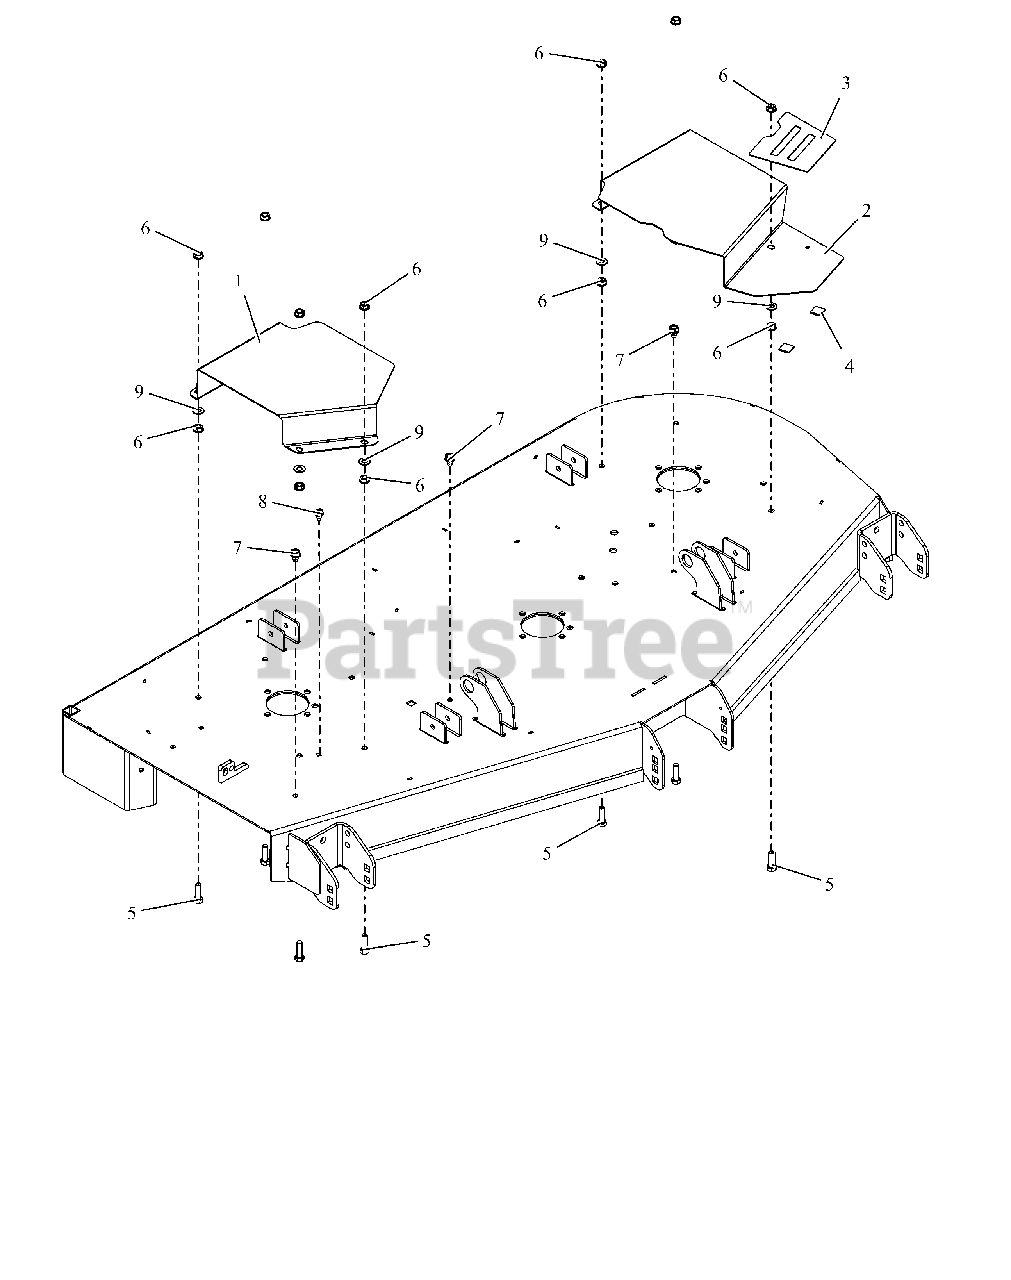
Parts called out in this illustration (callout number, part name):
1	COVER, BELT 52" & 60" RIGHT
2	COVER, BELT 60" LEFT
3	GRIP, TAPE 52-60 BELT COVER
5	BLT, HEX .38-16X1.25 G5 ZCC
6	NUT, SPNLK-FLG .38-16 G5 ZCC
7	SCR,TAP .375-16X.50 HWH TR ZCC
8	SCR,TAP .312-18X.50 HWH TR ZCC
9	WSHR,FLT .406X.812X.065 ZCC
